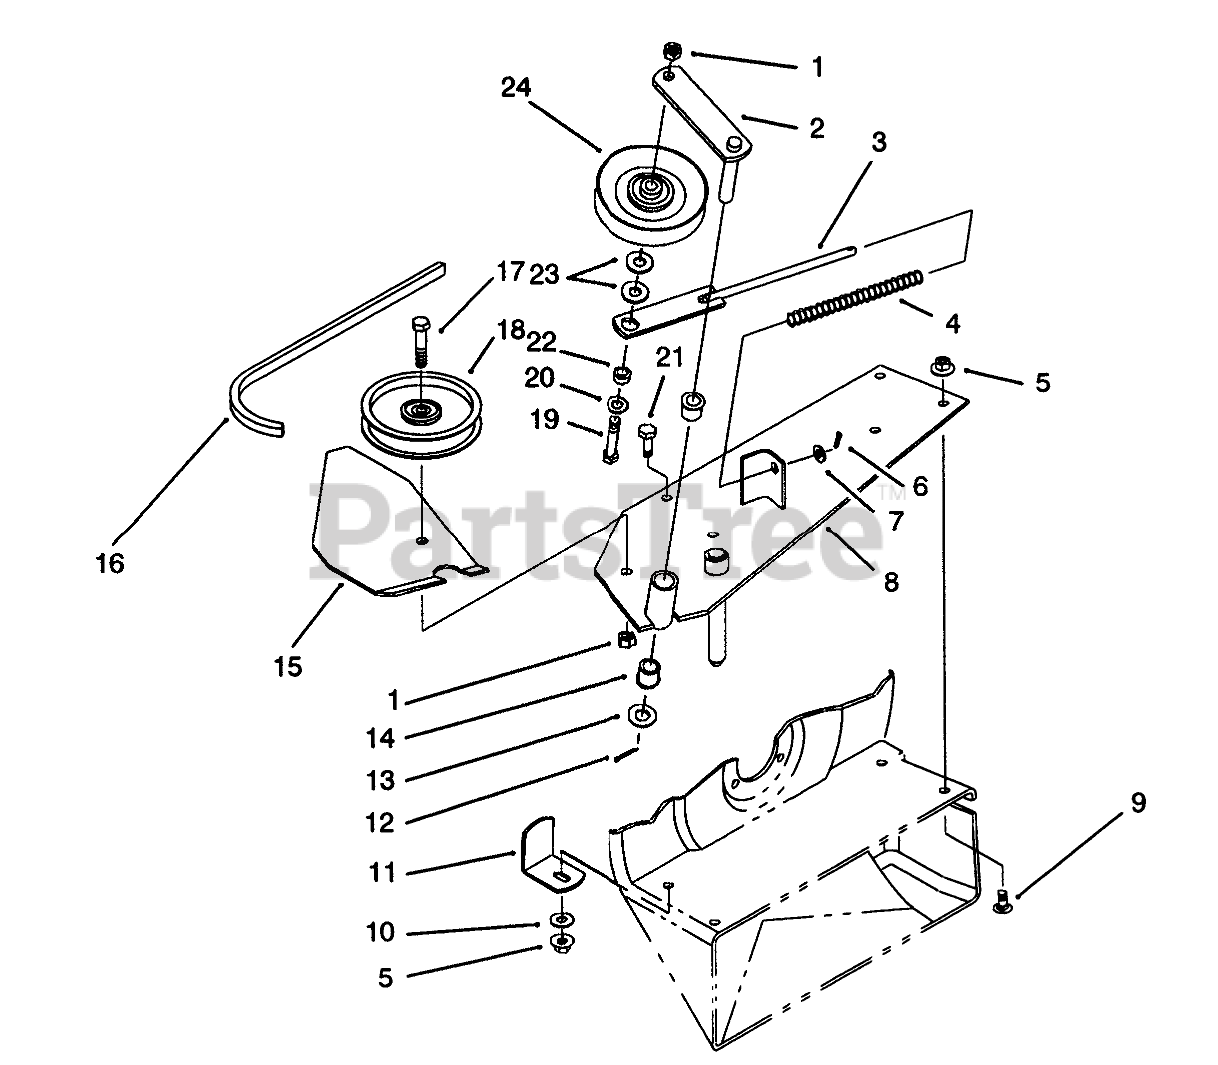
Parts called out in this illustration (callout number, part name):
1	NUT-LOCK, NI
2	IDLER ARM ASM
3	SPRING-ROD
4	SPRING-COMPRESSION
5	NUT-HF
6	PIN-COTTER
7	WASHER-PLAIN
8	BLOWER-MTG ASM
9	BOLT-CARR
10	WASHER-FLAT
11	BRACKET-SUPPORT, HOUSING
12	PIN-COTTER
13	WASHER-FLAT
14	BUSHING
15	SHIELD SUPPORT B
16	V-BELT
17	SCREW-HH
18	Pulley
19	SCREW-HH
20	WASHER-FLAT
21	SCREW-HH
22	SPACER
23	WASHER-FLAT
24	"V" Pulley
